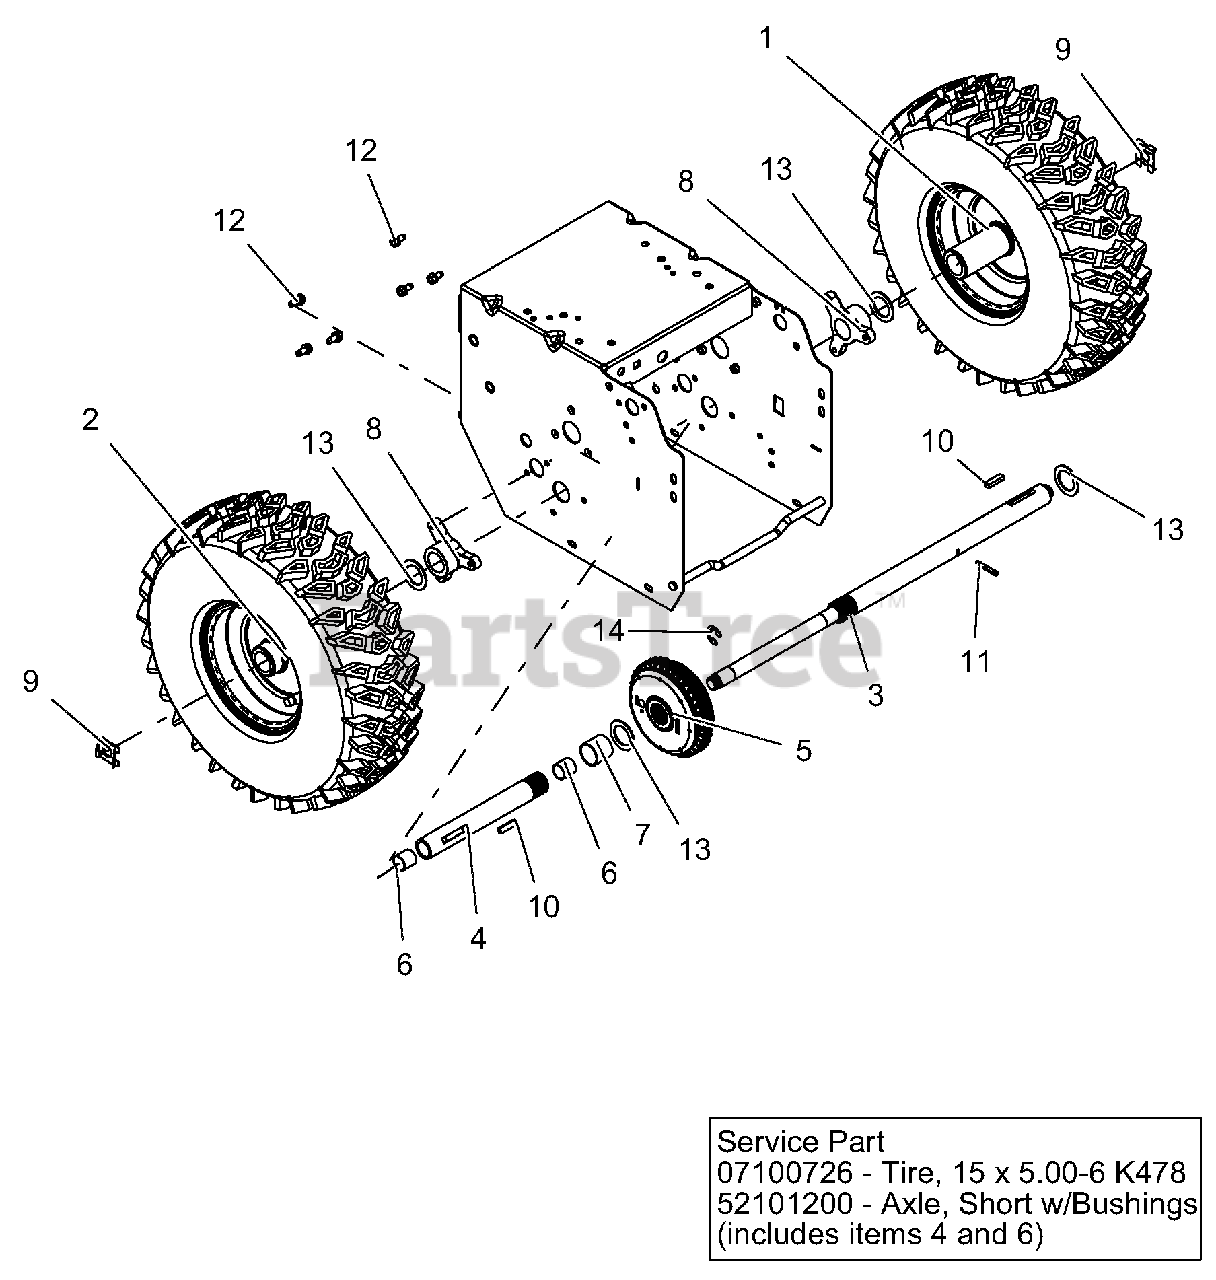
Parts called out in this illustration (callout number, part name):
1	TIRE/WHEEL,LH 15X5.00-6 REMOTE
2	TIRE/WHEEL,RH 15X5.00-6 REMOTE
2	TIRE, 15X5.00-6 K478
3	AXLE, LONG - DIFFERENTIAL
4	AXLE, DIFFERENTIAL W/BUSHINGS
5	DIFFERENTIAL, AUTOMATIC
6	BSHG-SLV .706X.764X.75 BRZ
7	BSHG-SLV, 1.012X1.125X1.00
8	BUSHING, AXLE
9	CLIP, SNAP .625 DIA
10	KEY-RECT .25X.188X1.00
11	PIN-ROLL .188X1.25
12	SCR-TAP .25-20X.50 HWH TR YWZ
13	WSHR-FL-STL 1.010X1.505X.062YZ
14	RG-RTNG-EXT .625X.042
